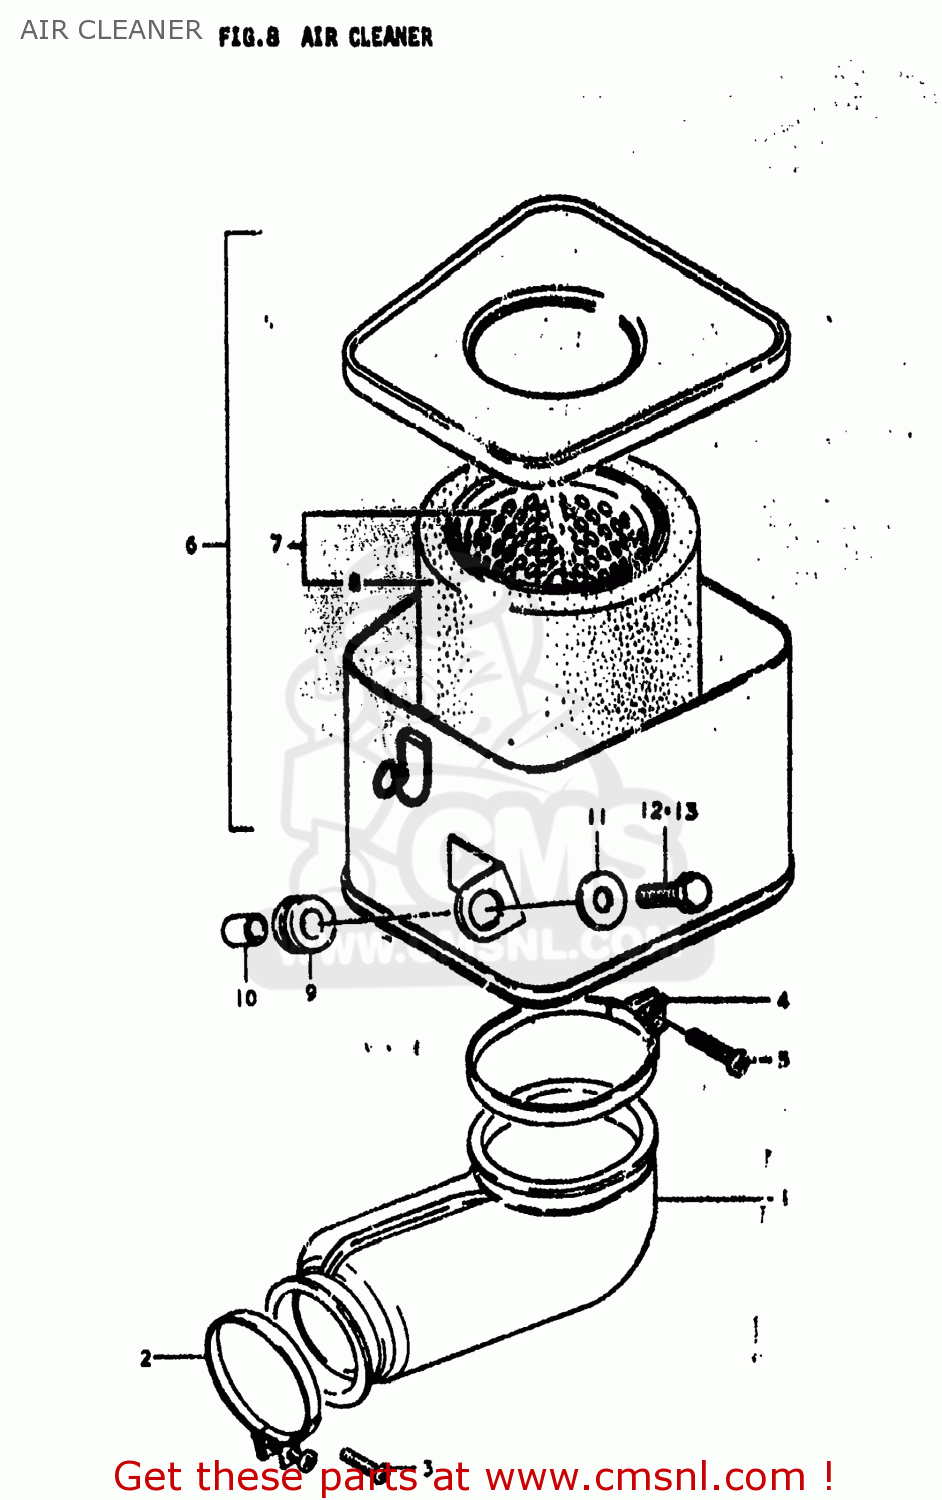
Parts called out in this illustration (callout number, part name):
1	TUBE,AIR CLEANER OUTLET
2	CLAMP
3	SCREW
4	CLAMP
5	SCREW
6	CLEANER ASSEMBLY,AIR
7	FILTER ASSY
8	FILTER
9	CUSHION
10	SPACER (7X9X7)
11	WASHER (6.5X20X1.2)
12	BOLT
13	BOLT
